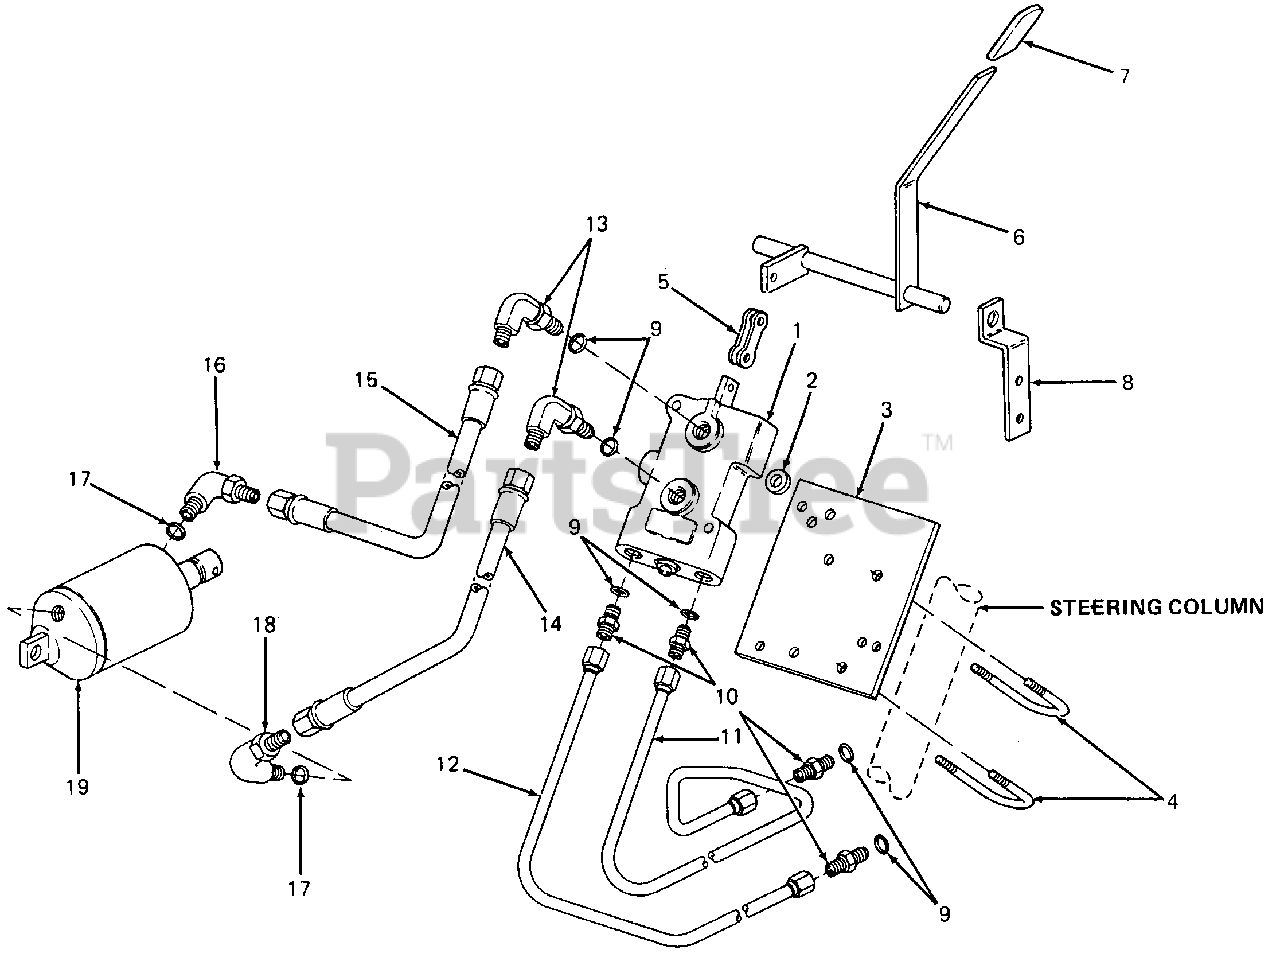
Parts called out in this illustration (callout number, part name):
1	Valve Assy, Control
2	Spacer, .267 X .406 X .375 Lg
3	Plate, Valve Support
5	Link, Chain
6	Handle Assy, Valve
8	Support, Valve Handle
9	O-Ring, 3/8 OD Tube
10	Connector, 37 Degree Tube
11	Tube Assy, Pressure
12	Tube Assy, Return
13	Elbow, Reducer, 3/8 to 1/4
14	Hose, Extending
15	Hose, Retracting
16	Elbow, 90 Degree w/O-Ring
17	O-Ring, 1/4 OD Tube
18	Elbow, 45 Degree w/O-Ring
19	Cylinder, Hydraulic
